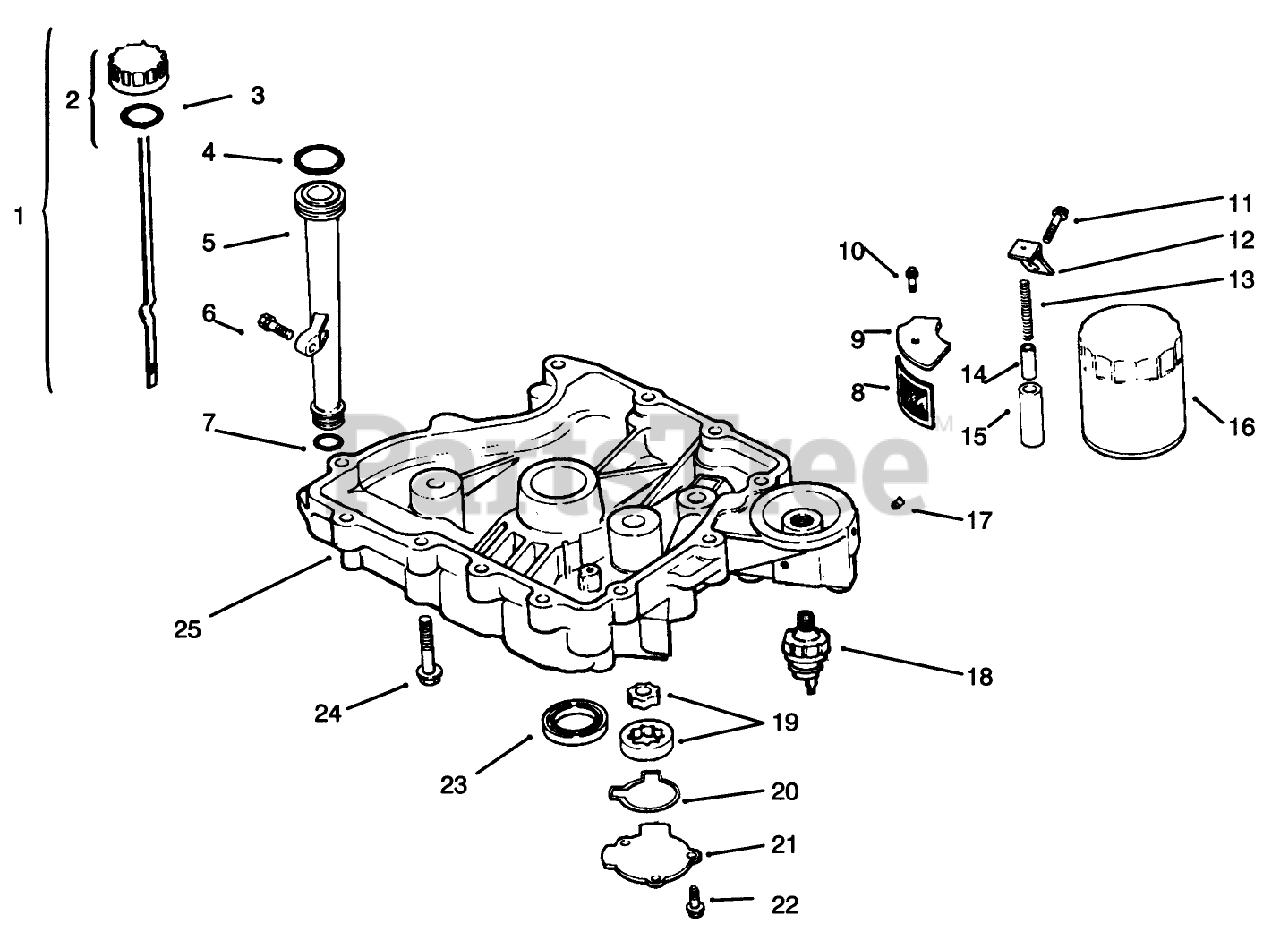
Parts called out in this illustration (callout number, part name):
1	Dipstick INC 2-3 (Only On: 72042, 72063, 72062, 72043)
2	Kit-Oil Fill Cap (Incl. Ref. #7)
3	ORing
4	O Ring-Upper Fill Tube (Only On: 72103)
5	Tube-Oil Fill (Only On: 72103, 72083)
7	O-Ring-Lower Fill Tube (Only On: 72042, 72063, 72062, 72043)
8	Screen-Oil Pickup (Only On: 72042, 72063, 72062, 72043)
9	Cover-Oil Pickup Screen (Only On: 72042, 72063, 72062, 72043)
10	Screw M5x0.8x16 (Only On: 72042, 72063, 72062, 72043)
11	Screw M10x1.5x25 (Only On: 72042, 72063, 72062, 72043)
12	Bracket-Oil Pump Relief (Only On: 72042,72043,72062,72063)
13	Spring-Oil Relief Valve (Only On: 72042,72043,72062,72063)
14	Piston-Oil Relief Valve (Only On: 72042, 72063, 72062, 72043)
15	Body-Oil Relief Valve (Only On: 72042, 72063, 72062, 72043)
16	Filter-Oil
18	Switch-Oil Pressure
19	Pump-Oil (Only On: 72042, 72063, 72062, 72043)
20	O Ring-Oil Pump Cover (Only On: 72042,72043,72062,72063)
21	Cover-Oil Pump (Only On: 72042,72043,72062,72063)
22	Screw M5x0.8x16 (Only On: 72042, 72063, 72062, 72043)
23	Seal-Crankshaft (Only On: 72042, 72043, 72062, 72063)
24	Screw M8x1.25x45 (Only On: 72042, 72063, 72062, 72043)
25	Pan-Oil (Only On: 72042,72043,72062,72063)
